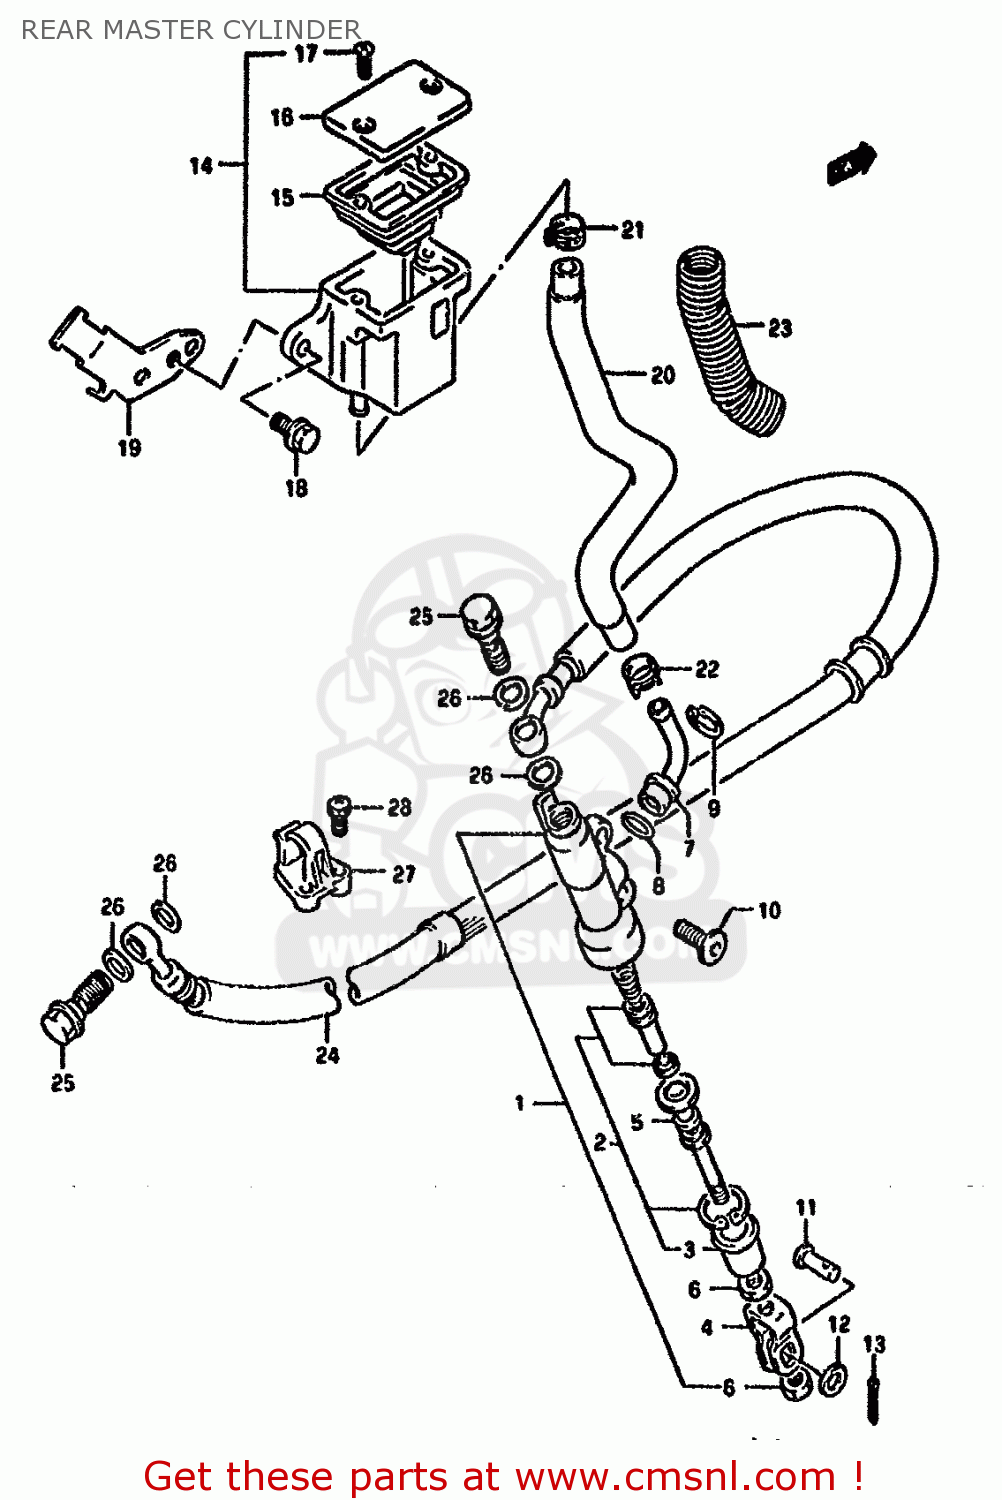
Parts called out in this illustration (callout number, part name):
1	CYLINDER ASSY,RR MASTER
2	PISTON/CUP SET
3	BOOT
4	YOKE
5	ROD,PUSH
6	NUT
7	CONNECTOR
8	O RING
9	CIRCLIP
10	BOLT(6X18)
11	PIN
12	WASHER
13	PIN
14	TANK ASSY,RESERVOIR
15	DIAPHRAGM
16	CAP
17	SCREW
18	BOLT
19	PLATE COMP,RESERVOIR T
20	HOSE COMP,RESERVOIR TANK
21	CLIP
22	CLIP
23	SHIELD,RESERVOIR TANK HOSE
24	HOSE COMP,REAR BRAKE
25	BOLT UNION
26	WASHER(10X15X1.5)
27	GUIDE,RR BRAKE HOSE
28	SCREW
